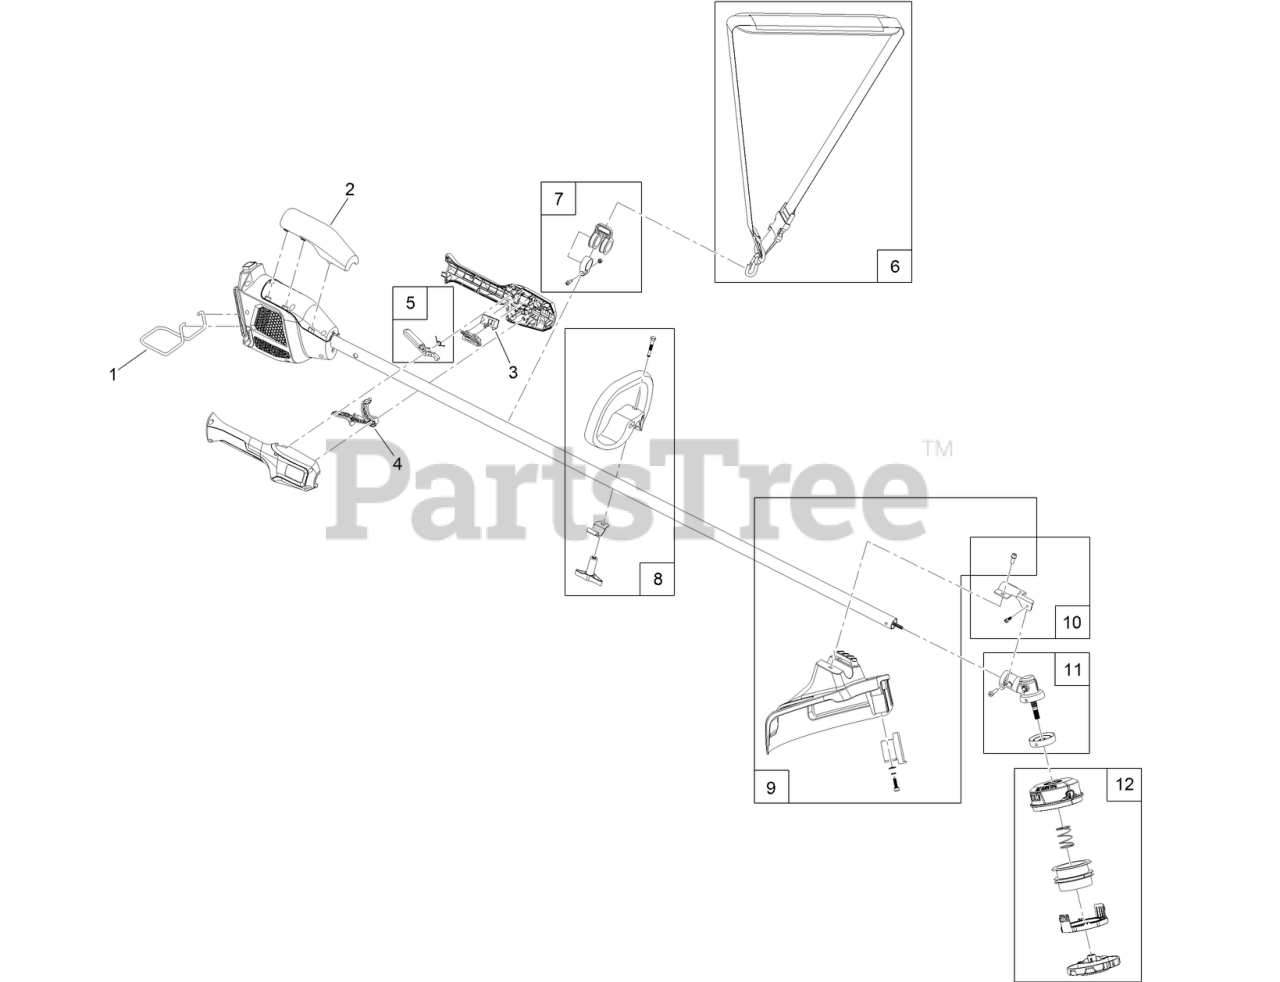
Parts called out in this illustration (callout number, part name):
1	GUARD-WIRE
2	COVER-MOTOR HOUSING
3	COVER-TWO SPEED SWITCH
4	PADDLE-SPEED CONTROL TRIGGER
5	PADDLE-LOCKOUT TRIGGER
6	SHOULDER STRAP
7	COLLAR-MOUNT, SHOULDER STRAP
8	HANDLE-ASSIST
9	GUARD-GRASS
10	BRACKET-MOUNT, GRASS SHIELD
11	GEAR CASE-STRING TRIMMER, LOWER HEAD
12	HEAD-BUMP
